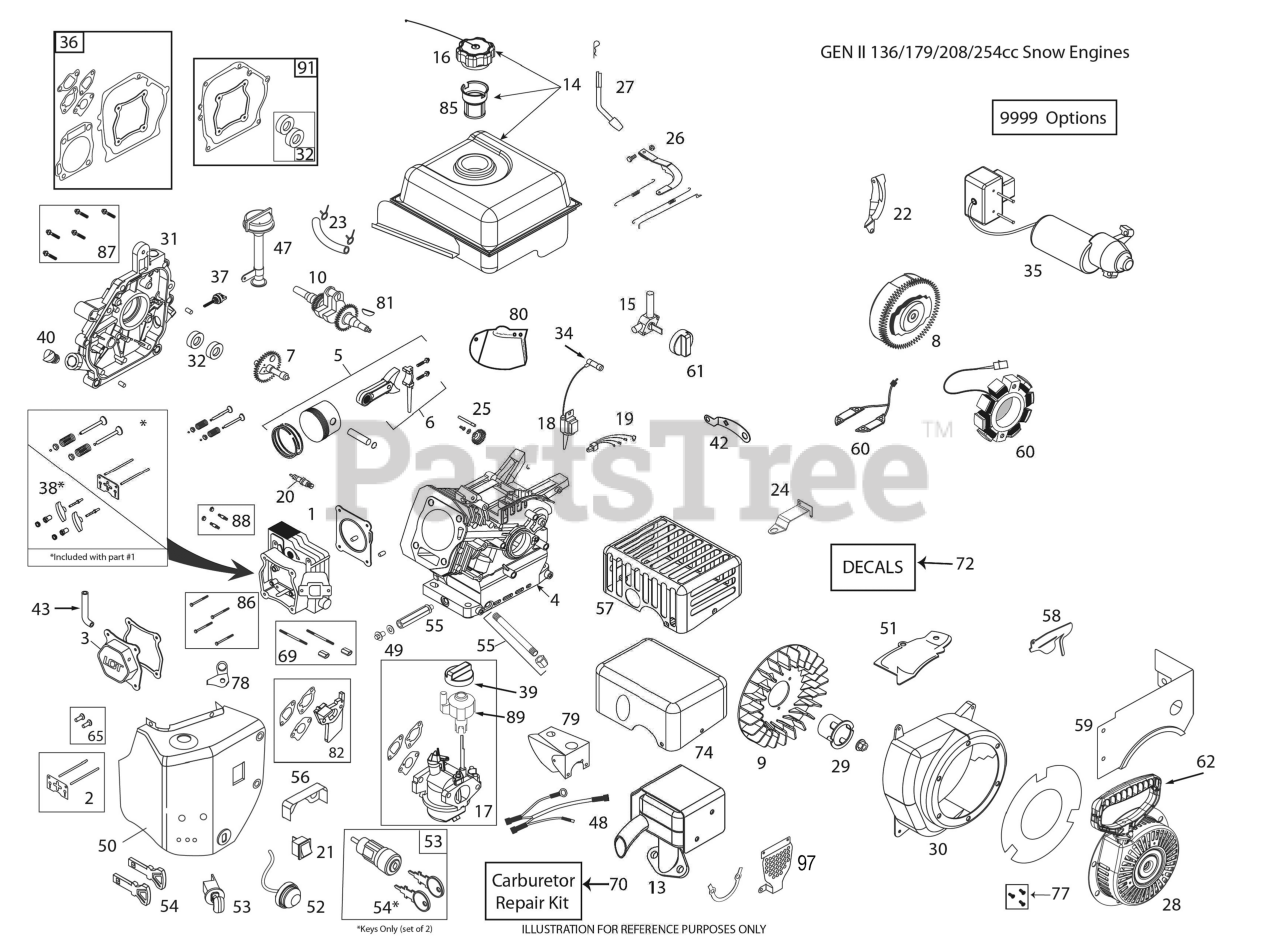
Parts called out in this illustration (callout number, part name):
1	CYLINDER.HEAD.ASM.W/GASKET.254
2	KIT.PUSH.ROD.&.PLATE.W/VC.GASK
3	COVER.VALVE.W/GASKET.254CC
5	PISTON.&.ROD ASSEM.254CC
7	CAMSHAFT.MCR.W/GASKET.254CC
8	FLYWHEEL.ELEC.STRT.(8.MAGNETS)
9	FLYWHEEL FAN 420586
10	CRANKSHAFT.KEYED(#18).SNOW.254
13	MUFFLER.ASSEM.GEN2.SNOW.254CC
14	FUEL.TANK.SNOW.2.7L.BLACK.254C
15	FUEL.PETCOCK.SNOW(SKSN4900)
16	FUEL CAP OVERSIZED CLICK STYLE
17	CARBURETTOR LCT 254 W/IDLEDOWN
18	COIL.ING.CDI.HI TEMP.SKSNO416.
20	PLUG.SPARK.PLAT.SKSN2404.1
21	SWITCH.ON/OFF(SKSN-0403)
22	SHIELD.FLYWHEEL.ELEC.STRT.208C
23	KIT.FUEL.HOSE.208CC.SING/STAGE
24	BRACKET.SPEED.CNTRL.FIXED.254C
25	GOVENOR.GEARS ASM(SK2082900)
26	KIT.GOVERNOR.ARM.&.LINK.254CC
27	KIT.GOVERNOR.CRANK(SK208-3100)
28	RECOIL.STRT.ROUND(BLK) SNOW
29	STRTER.CUP(NON-SLOT)SKSN0601.2
30	BLOWER HSG.LCT 254 GLOSS BLK S
31	CRANKCASE.CVR.PRESS.IN.HI-OIL.
32	KIT.SEAL.OIL.2.PIECES.254CC
34	SPARK.PLUG.BOOT.SNW,SKSN4691.1
35	STARTER 230C EL START.LCT SKSN
35	STARTER.EL.230C.SNO.LCT.208CC.
35	STARTER.ELECTRIC 120V
35	ELEC.START.GEN2.SKSN0451.1
36	KIT.ENGINE.GASKET.254CC
38	KIT.ROCKER.ARM.W/GASKET.254CC
39	CHOKE.KNOW.SNOW(SKSN4500)
40	NON REMOVABLE PLUG
43	TUBE.BREATHER.LCT.208
47	TUBE ASSY HIGH OIL-FILL
48	HARNESS WIRE. W/O OFF/ON SWITC
48	WIRE.HARNESS.SNOW
49	KIT.OIL.DRAIN.PLUG(SK2089911
51	SHIELD.CYLINDER.COVER.254CC
52	PRIMER.BULB.WITH HOSE (SNOW)
53	SWITH.KEY.ASSEM.SNOW.SINGLE.ST
54	KEY SET(2 KEYS) SKSN0407.1
55	OIL PIPE DRAIN LCT 254
55	EXTENDED OIL DRAIN TUBE
57	SHIELD.MUFFLER.CE.COMPLIANT
58	SHIELDS
59	SKIRT.FUEL.TANK.SNOW.254CC
59	FUEL TANK SKIRT SHIELD LCT 254
60	208CC 60W ALTERNATOR
61	FUEL KNOB-SNOW
62	HANDLE.RECOIL.DELUXE.LCT
65	TAPPET.KIT.LCT.208CC
69	CARB.STUDS & COUPLING KIT.SNOW
70	CARB.REPAIR.KIT.LCT.SK9900.2
72	KIT.ENGINE.DECAL.208CC.LCT.SK1
74	COVER.MUFFLER.HEAT.SHIELD.
74	MUFFLER GUARD.EUR./LCT.SKSN220
77	BOLT.KIT.RECOIL.LCT.ALL.ENGINE
81	KEYS.FLYWHEEL.208/414CC.5PACK
82	SPACER.CARBURETOR.208CC.LCT
85	STRAINER.FUEL.TANK.LCT.208CC
86	KIT.BOLT.CYLINDER.HEAD.(4PC)
87	KIT.BOLT.CRANKCASE.COVER.6PC
88	STUD.MUFFLER.KIT.LCT
89	KNOB LCT.SKSN5325.1 SPEED
91	CRANKSHAFT GASKET KIT.LCT
97	GUARD.MUFFLER.MANIFOLD.LCT
9999	JET HIGH ALTITUDE LCT 5000 25
9999	STARTER SCREW.STARTER SWITCH B
9999	KIT.BOLT.LCT.SK9990.1
